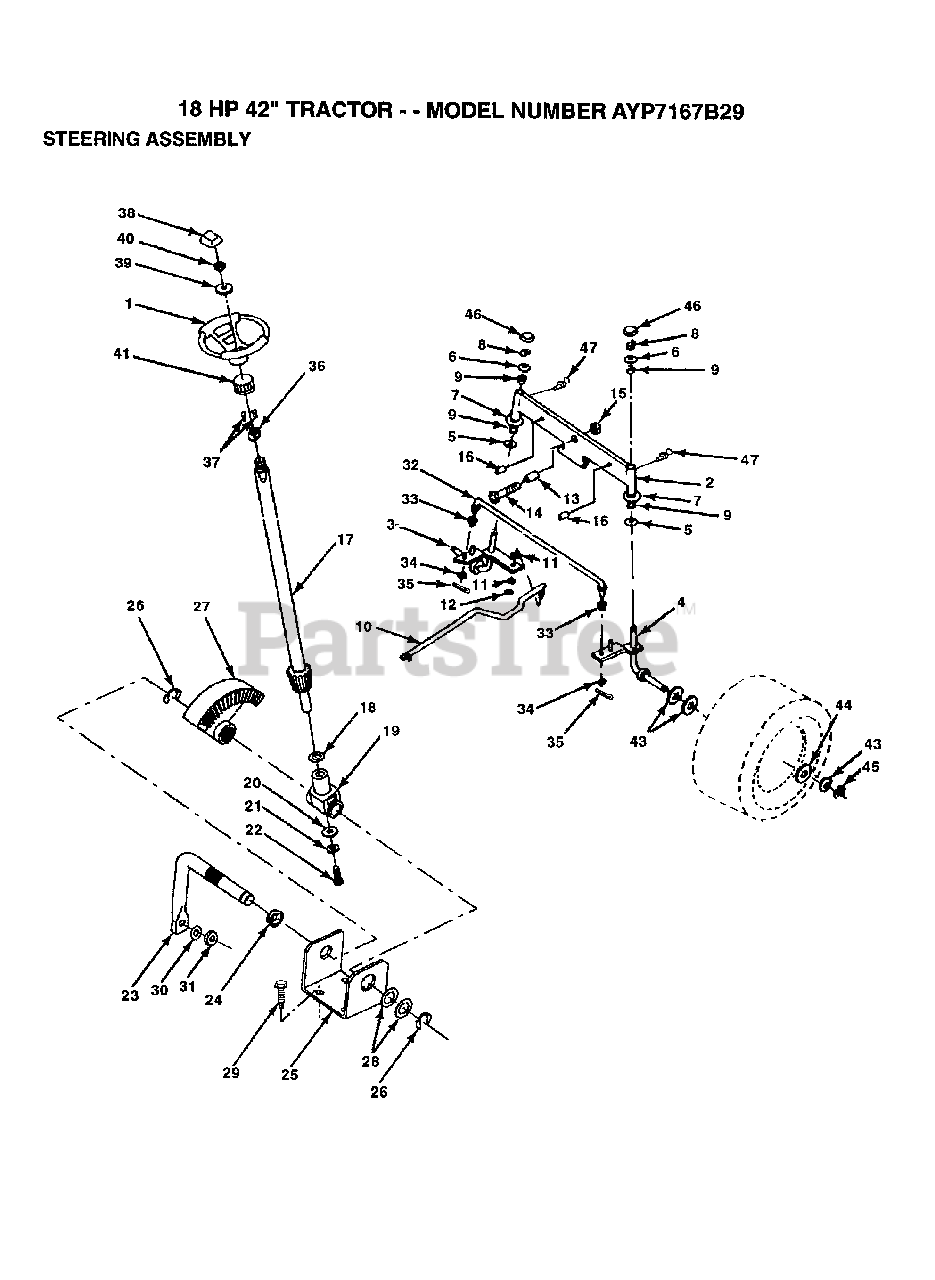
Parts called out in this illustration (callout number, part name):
3	SPINDLE LH
4	SPINDLE RH
5	WASHER .T
6	WASHER
7	WASHER
8	RING
9	COL. SRTG. BEAR.
11	LOCKWASHER
13	BEARING
14	BOLT HEX 5/8-11
16	AXLE PIN
17	STEERING SHAFT
18	THRUST WASHER
19	SUPPORT.SHAFT
21	LOCKWASHER
22	"SCREW,SPECIAL"
24	NYLINER T
25	"BRKT,STEERING"
26	RING
28	WASHER .T
29	SCREW
30	LOCKWASHER
32	TIE ROD
33	BUSHING.DRAGLINK
34	WASHER
35	COTTER PIN
38	ST WHL INSERT CAP
39	WASHER
41	ADAPTER LT
43	WASHER
44	WASHER
45	RING
46	CAP
47	ZERK M
